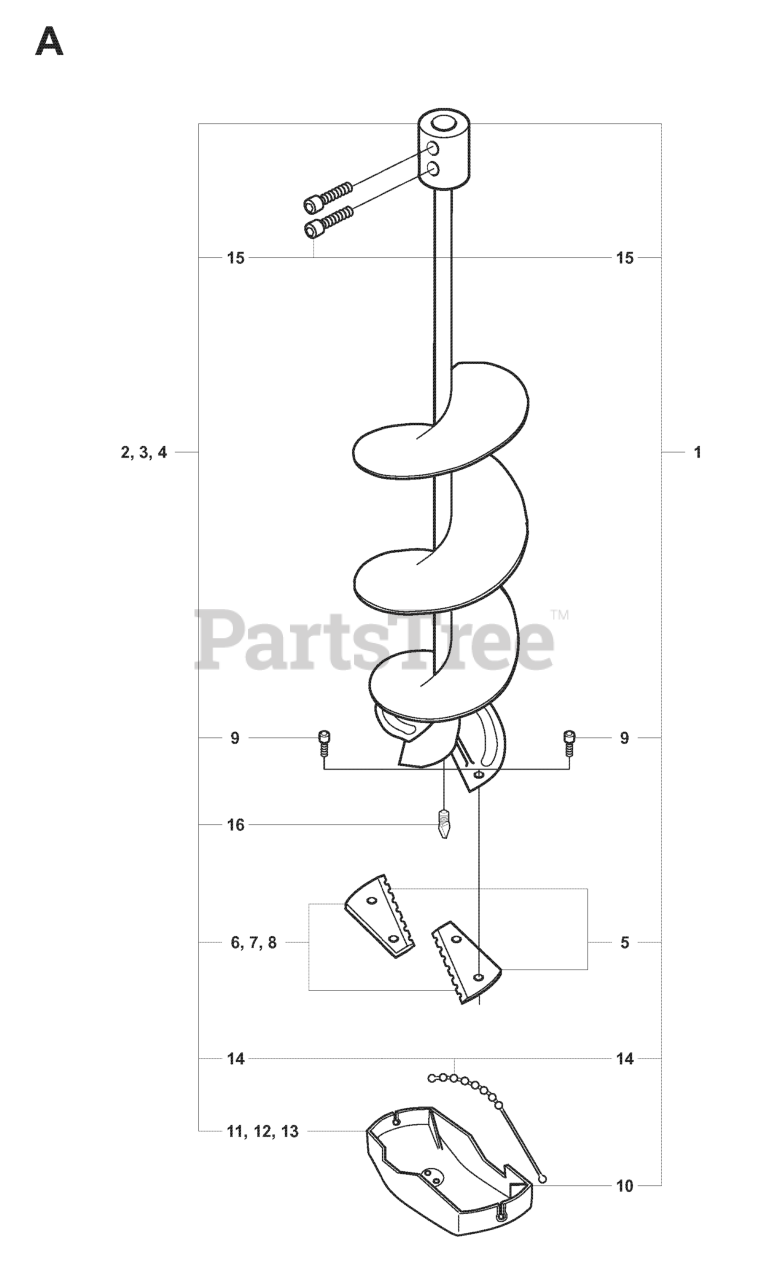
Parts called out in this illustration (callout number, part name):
2	6" ICE AUGER BIT
3	8" ICE AUGER BIT
4	10" ICE AUGER BIT
5	BLADE 130MM
6	6" ICE KNIFE
7	8" ICE KNIFE
8	10" ICE KNIFE
10	PROTECTOR 130MM
11	PROTECTOR 150MM
12	PROTECTOR 200MM
13	PROTECTOR 250MM
